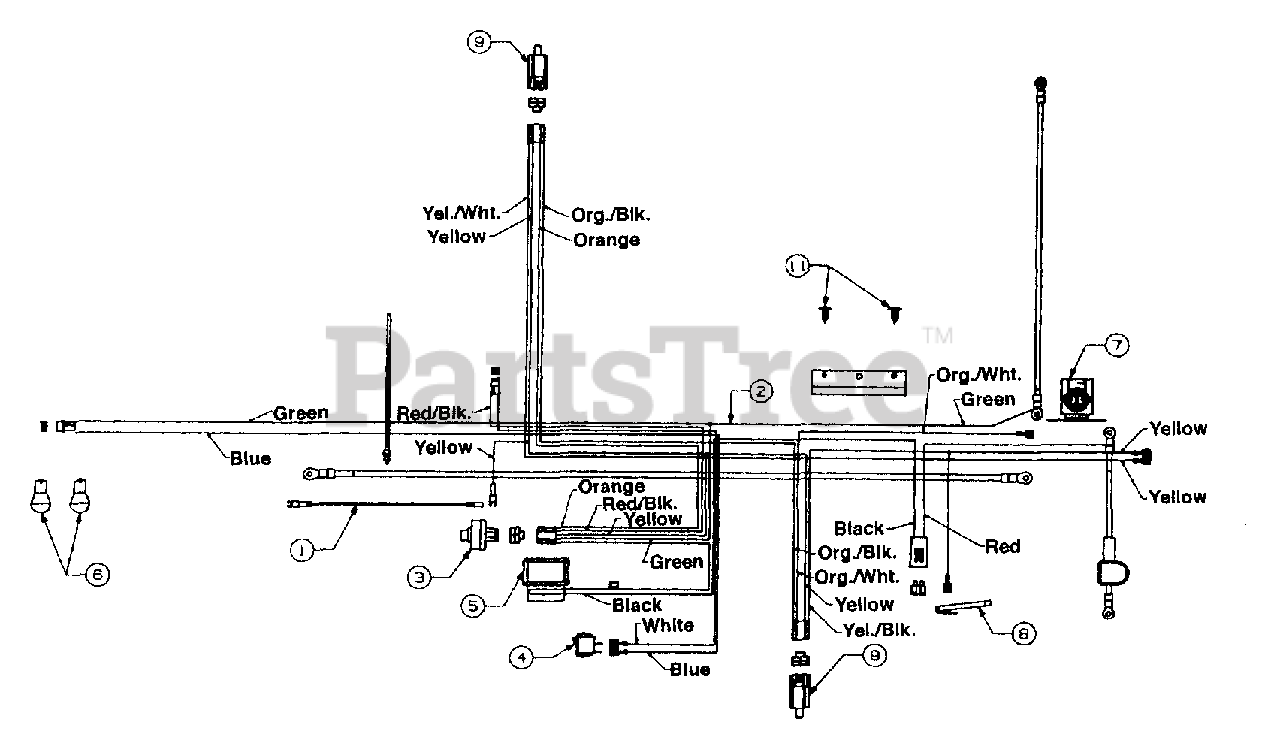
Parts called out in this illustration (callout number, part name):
1	Harness Adapter (Mag.)
2	Wire Harness w/Light Switch and Amp
3	Ignition Switch
4	Light Switch
5	Ammeter
6	Bulb (Headlight)
7	Solenoid
8	Safety Switch (Reverse)
9	Safety Switch
11	Ratchet
